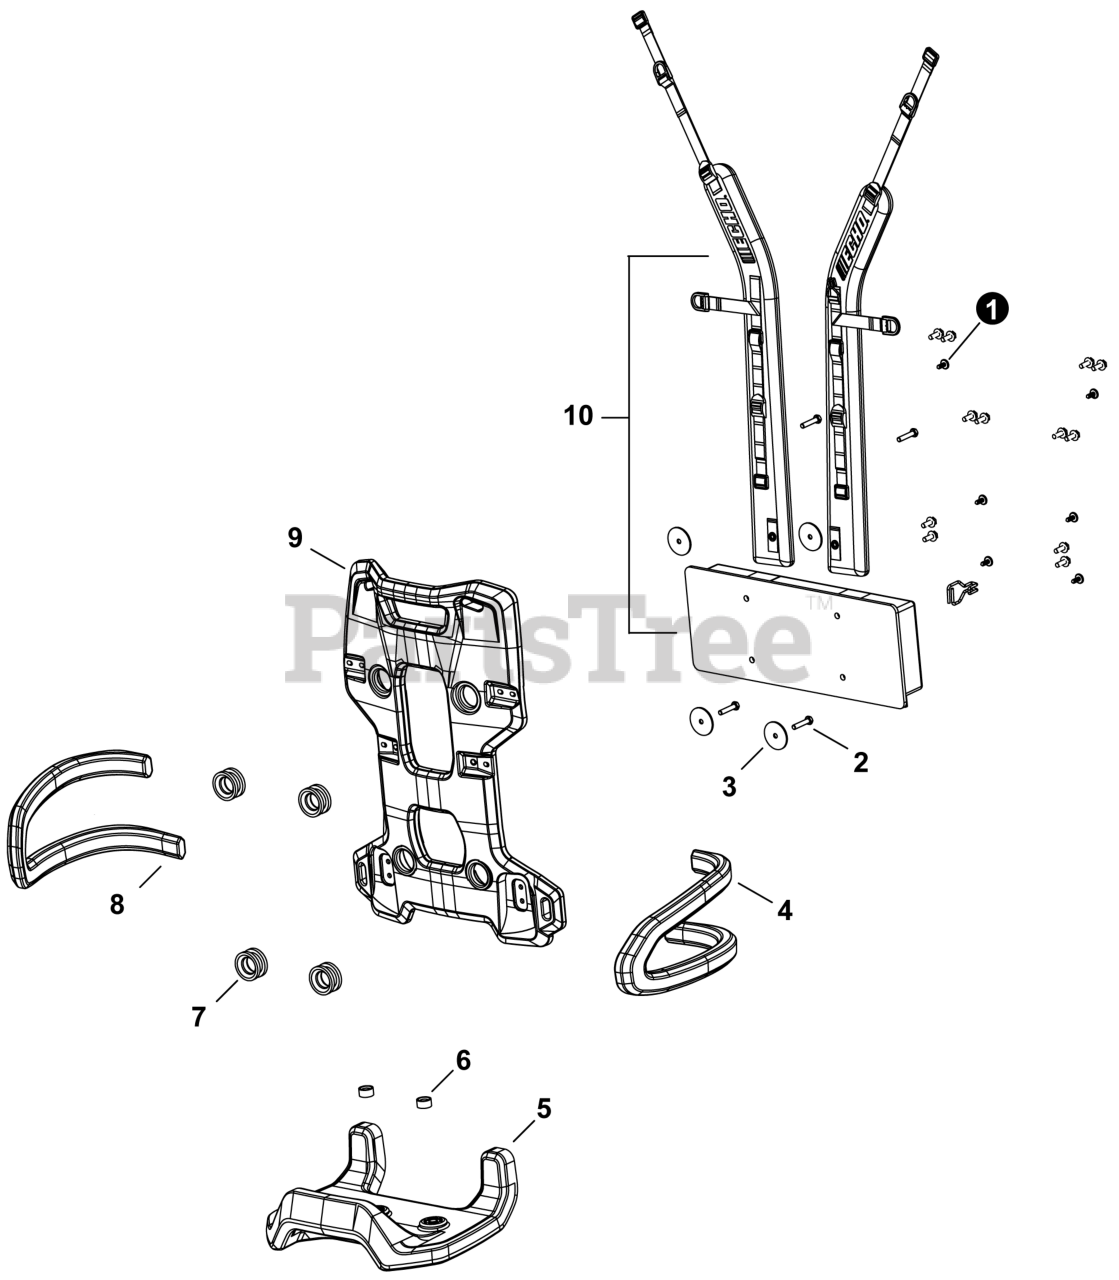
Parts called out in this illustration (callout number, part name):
3	WASHER, RUBBER
4	FRAME, RIGHT
5	FRAME, LOWER
8	FRAME, LEFT
10	ASSY., SHOULDER HARNESS
